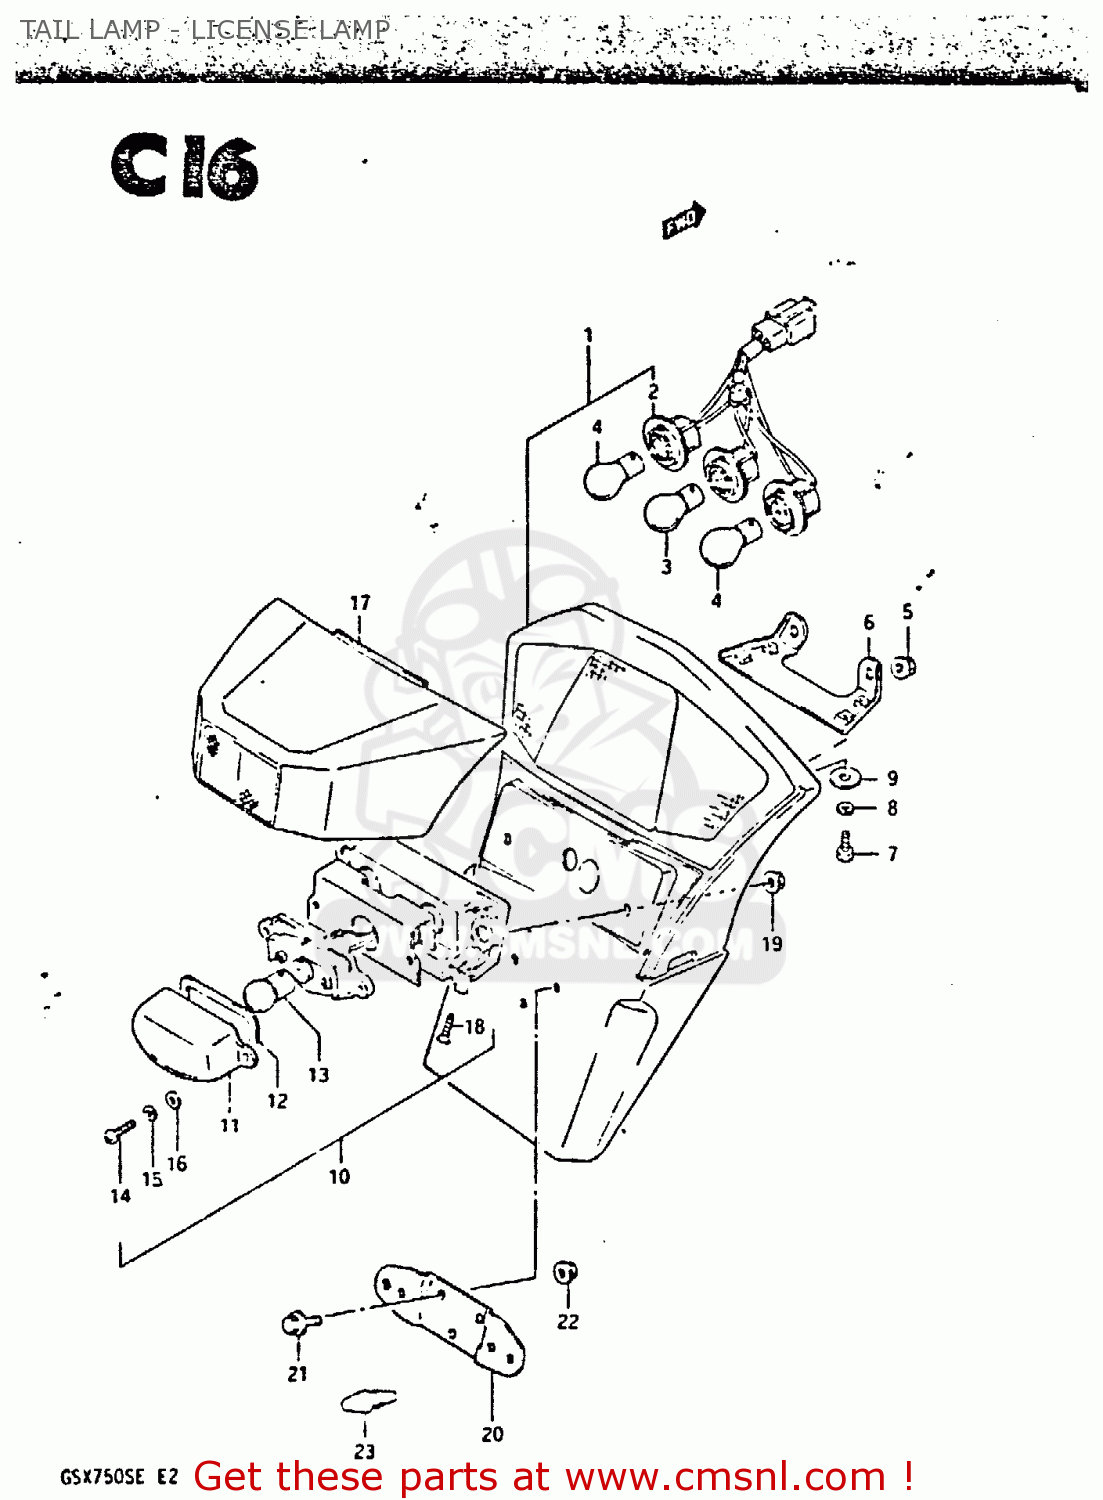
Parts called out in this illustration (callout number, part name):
1	LAMP ASSY, REAR COMBINATIO
2	SOCKET
3	BULB(12V23/8W,TOKAI DENSO)
4	BULB(12V23W,STANLEY,A4577A)
5	NUT
6	BRACKET, TAIL LAMP
7	BOLT
8	WASHER,LOCK
9	WASHER(6.5X16X1.2)
10	LAMP ASSY, LICENSE
11	LENS,LICENSE LAMP
12	GASKET,LICESE LAMP (NAS)
13	BULB
14	SCREW
15	WASHER,LOCK 4M
16	WASHER 4MM
17	COVER,LICENSE LAMP
18	SCREW
19	NUT
20	BRACKET, LICENSE PLATE
21	BOLT
22	NUT
23	CUSHION
